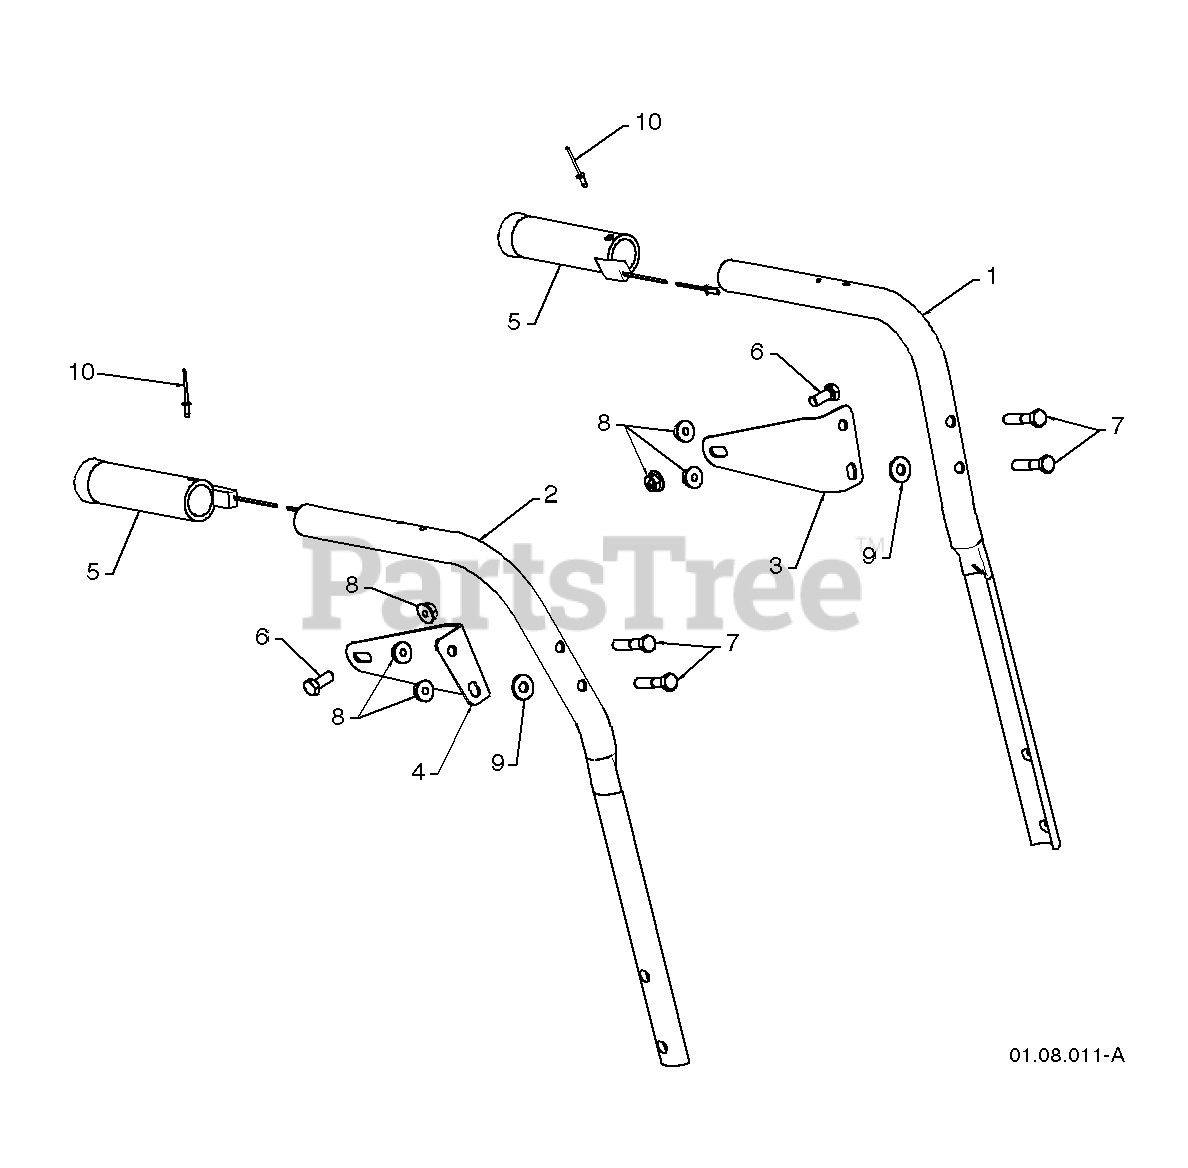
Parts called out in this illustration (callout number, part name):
1	PLOW HANDLE LH
2	PLOW HANDLE RH
3	PANEL BRACKET LH
4	PANEL BRACKET RH
5	HEATED HANDLE GRIP
6	SCREW 5/16-18 X .750
7	SCREW 5/16-18 X 1.50
8	NUT 5/16-18
10	POP RIVET 1/8
